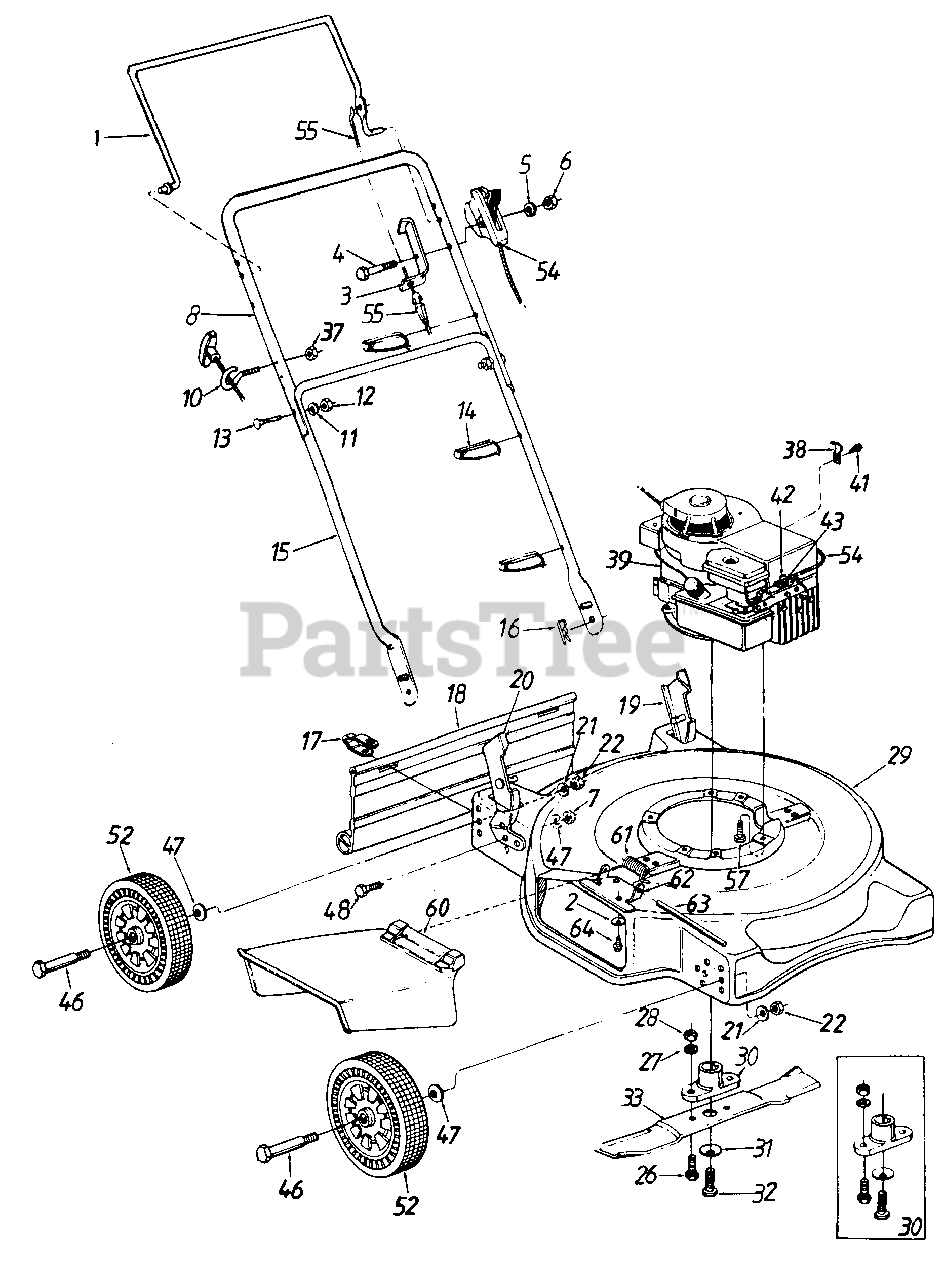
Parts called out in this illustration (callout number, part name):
1	Control Handle Ass'y.
2	Bell-Wash. 1/4" I.D.
3	Cable Brkt.
4	Hex Bolt 1/4-20 x 1.875" Lg.
5	Spr. Wash. 1/4" I.D.
6	Hex Nut 1/4-20 Thd.
7	Hex L-Nut 3/8-24 Thd.
8	Upper Handle
10	Rope Guide
11	L-Wash. 5/16" I.D.
12	Hex Nut 5/16-18 Thd.*
13	Curved Carriage Bolt 5/16-18 x 1.38" Lg.
14	Cable Tie
15	Lower Handle
16	Hairpin Cotter
17	Hinge Clip
18	Rear Flap
19	Handle Bracket Ass'y.-L.H.
20	Handle Bracket Ass'y.-R.H.
21	Bell-Wash..39" I.D.
22	Hex Nut 3/8-16 Thd.
26	4ex Bolt 3/8-24 x 1" Lg.
27	L-Wash. 3/8" I.D.
28	Hex Nut 3/8-24 Thd.
31	Bell-Wash. .39" I.D.
32	Hex Bolt 3/8-24 x 1.5" Lg.
33	20" Blade
37	Hex L-Nut 1/4-20 Thd.
38	Cable Clamp
39	Engine
41	Hex B-Tap Scr. #10 x .38"
42	Cable Clamp
43	Hex AB-Tap Scr. #8 x .38"
46	Axle Bolt
47	Bell-Wash. .400" I.D. x .88"
48	Hex Bolt 3/8-24 x .88" Lg.
52	Wheel Ass'y. Comp.
54	Throttle Control Ass'y. Comp. - 51.62"
55	Control Cable-36"
57	Hex L-Wash. Hd. Scr. 3/8-16 x 1.0" Lg.
60	Chute Deflector Ass'y.
61	Torsion Spring
62	Adapter Plate
63	Hinge Pin
64	Hex Self-Tap Scr. 1/4-20 x .5" Lg.
